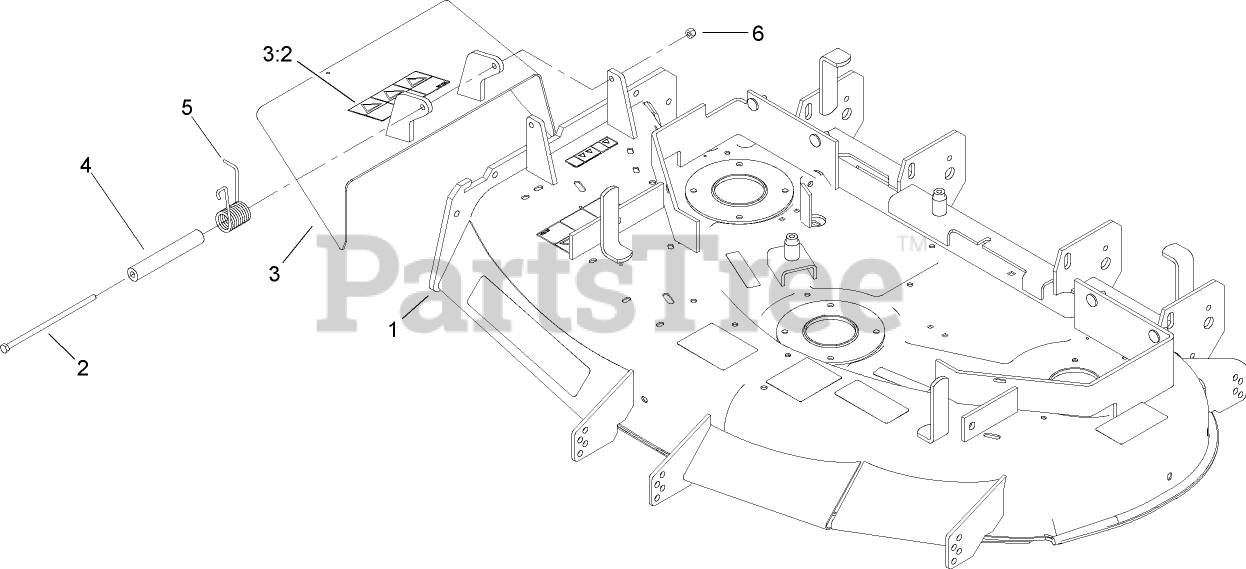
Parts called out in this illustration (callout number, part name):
1	DECK DECAL ASM
2	SCREW-HH
3	Deflector ASM
3:2	DECAL-DANGER
4	SPACER
5	SPRING-TORSION
6	NUT-LOCK, NI
